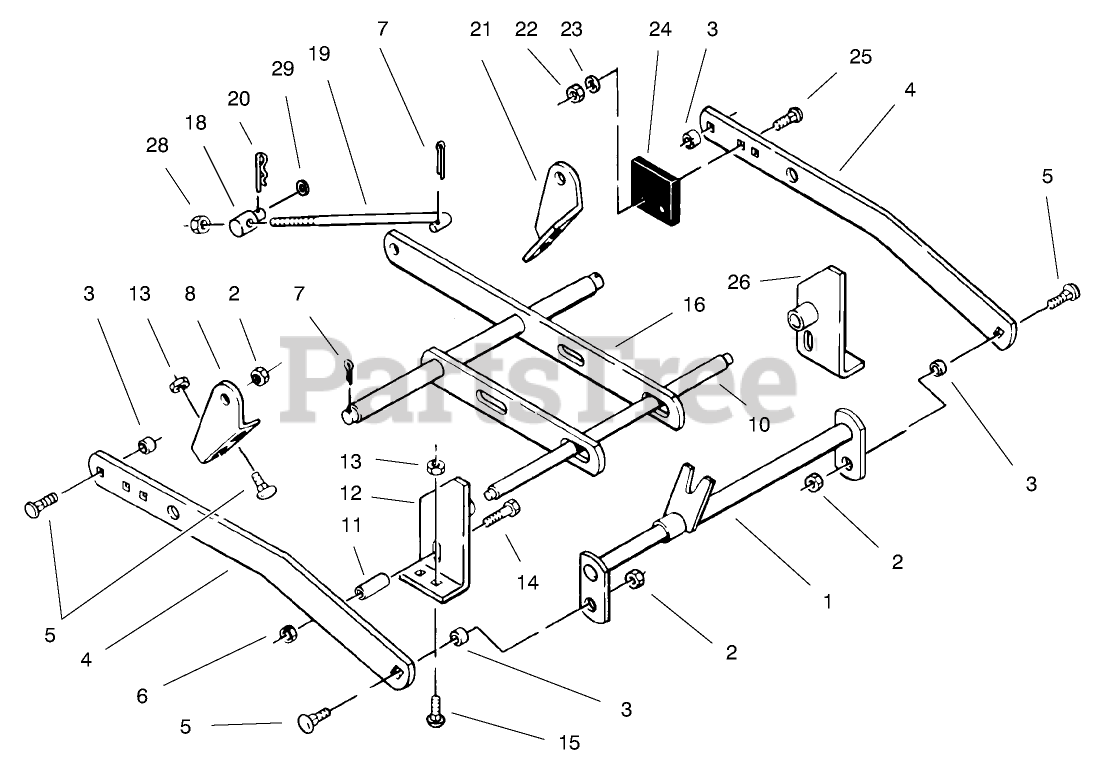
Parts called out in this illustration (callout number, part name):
1	WA HITCH
3	SPACER
4	BAR DRAFT
5	BOLT-CARR
6	NUT-LOCK, NI
7	PIN-COTTER
8	BRACKET-DCK R
11	SPACER
12	WA-RH FRT DK BRK
13	NUT-LOCK, NI
14	BOLT-CARR
15	BOLT-CARR
16	WA-LEVELER BAR
18	TRUNNION
19	LIFT ROD
20	PIN-HAIR
21	BRACKET-DCK L
22	NUT-LOCK, NI
23	WASHER-FLAT
24	BUMPER
25	SCREW-CARR
26	WA-LH FRT DK BRK
28	NUT-LOCK, NI
29	WASHER-FLAT
